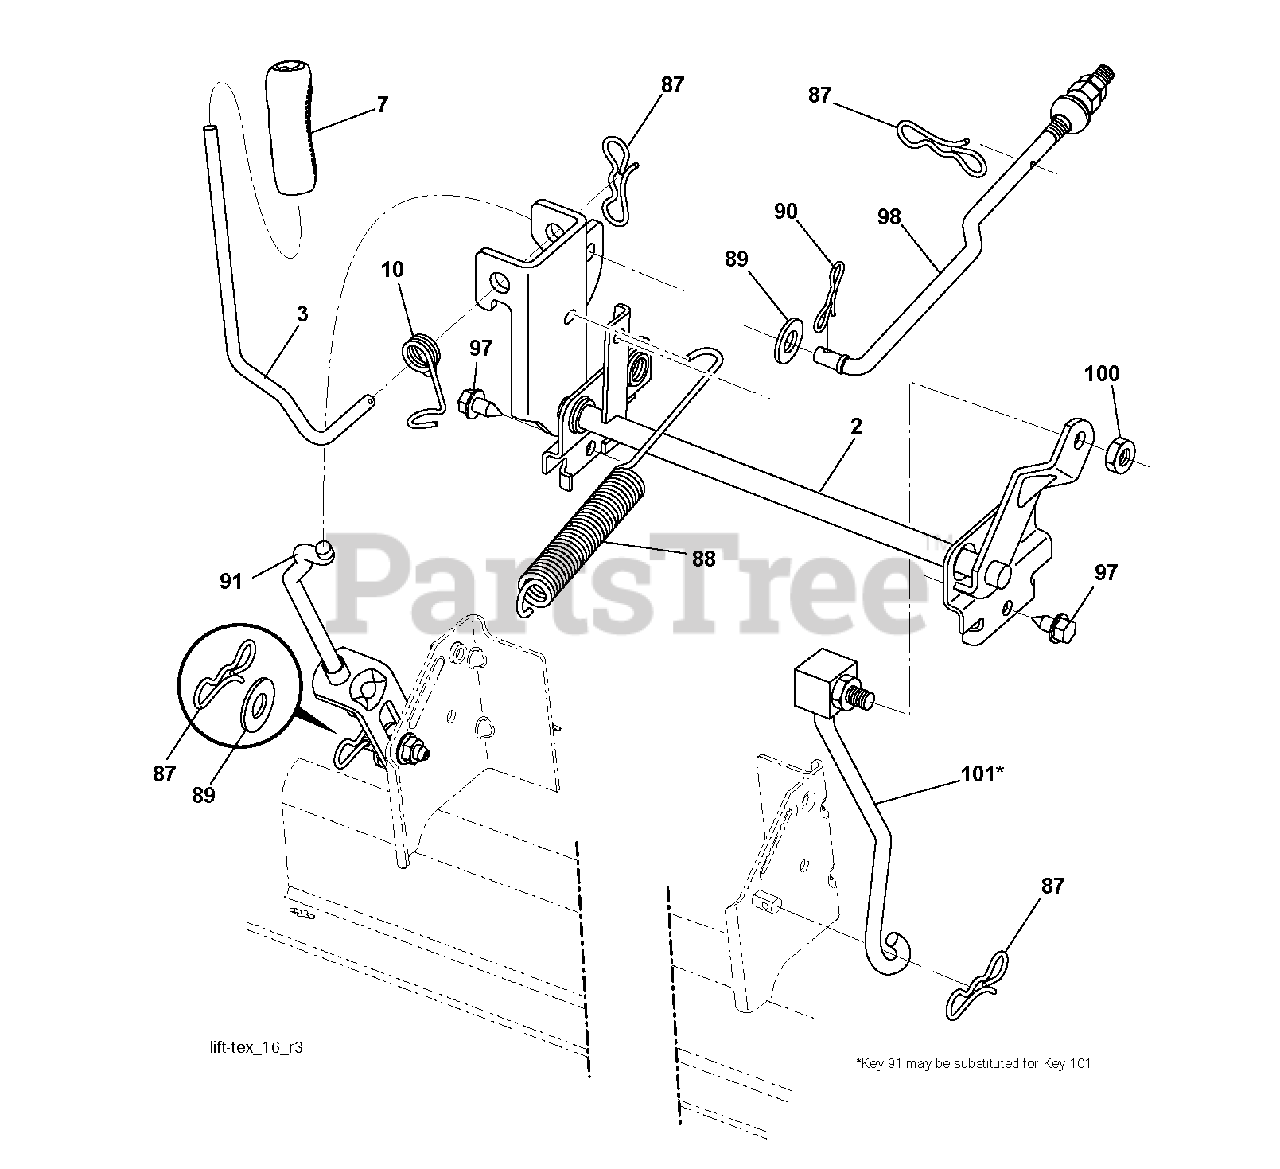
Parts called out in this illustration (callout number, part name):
2	SHAFT.ASM.LIFT.CROSS.H
3	LEVER.LIFT.HANDLE.LT
7	GRIP.HANDLE.LIFT.PVC.BLACK
10	SPRING.TORSION.LIFT.HANDLE
87	PIN.COTTER.7/16.BOW TI
88	SPRING.LIFT.ASSIST
89	WASHER.CLEAR.ZINC
90	PIN.COTTER.5/16.BOW TI
91	LINK.ASM.LIFT.REAR
97	SCREW, 3/8-16X3/4
98	LINK.ASM.SUSP.FRONT.MWR.10.5
100	LOCKNUT
101	LINK.ASM.LIFT.FIXE.38/42/46"
